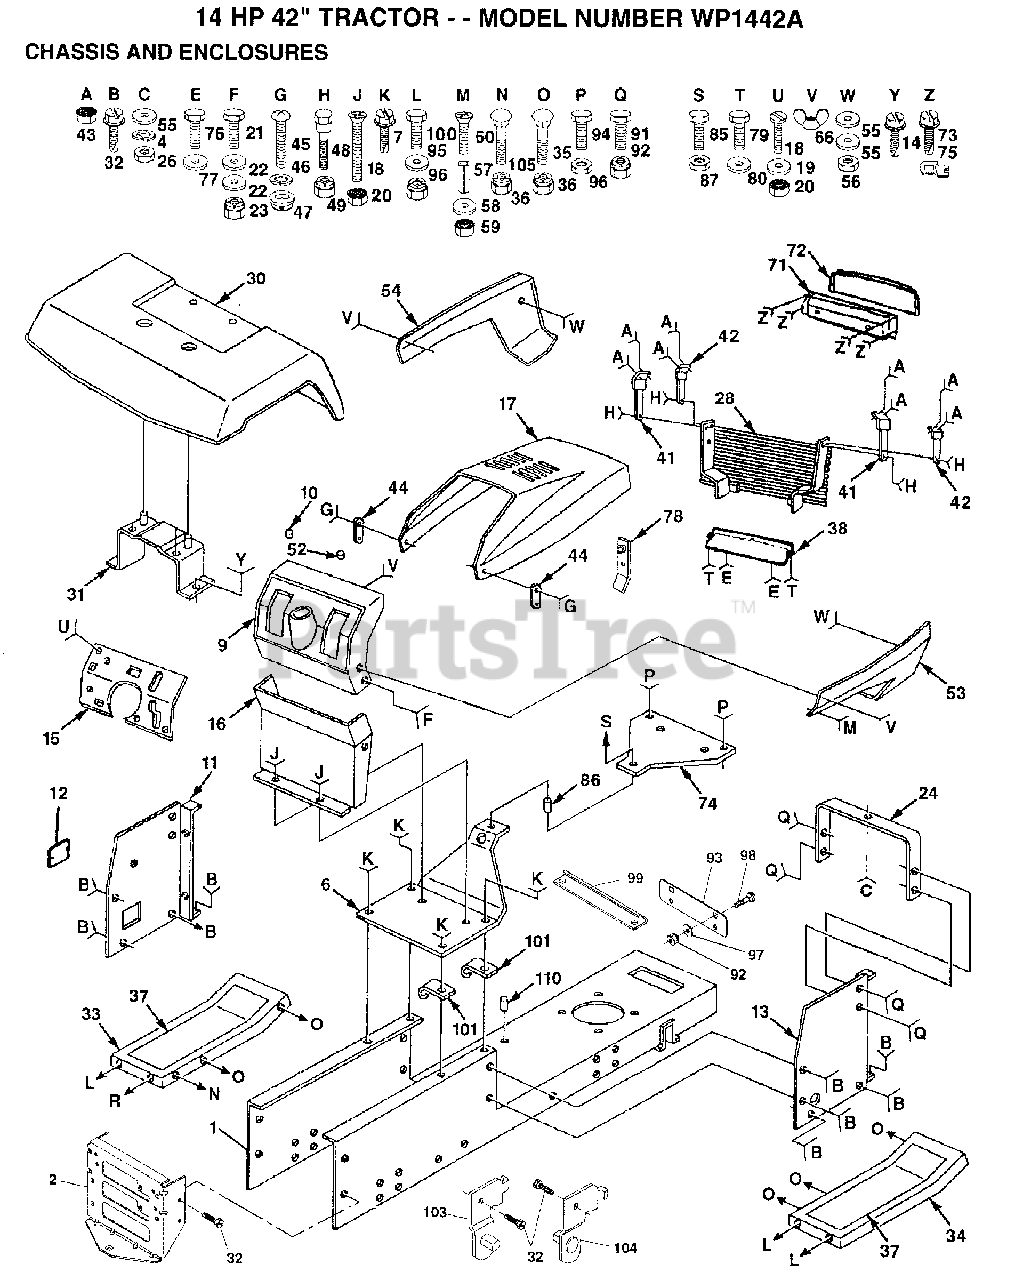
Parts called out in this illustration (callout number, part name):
4	LOCKWASHER
7	SCREW
9	DASHBOARD BLACK
10	PLUG BUTTON T
11	PANEL.DASH.LH
12	COVER ACCESS
13	PANEL.DASH.RH
14	SCREW
15	PLATE.DASH.SILKSC
16	DASH ASSY LT
18	SCREW
19	WASHER
21	BOLT
22	WASHER
23	NUT
24	SUPPORT ASS'Y
30	FENDER
31	BRACKET SUPT FEND
32	SCREW
35	BOLT
36	NUT
37	FOOTREST PAD
43	NUT
44	HOOD LATCH T
45	SCREW
46	LOCKWASHER
47	WELDNUT
52	PLUG-DASH T
54	"PANEL,SIDE LH"
55	WASHER PM
57	SPACER LT
58	WASHER
60	SCREW
72	LENS LT
74	PLATE.SUPT.BATTER
75	"""J"" FASTENER LT"
76	SCREW
77	WASHER
79	SCREW HEX CRT
80	WASHER
85	BOLT
86	SPACER
87	NUT
91	BOLT
92	NUT
93	PLATE EXTEN FEND
94	BOLT
95	WASHER
96	NUT
97	WASHER
99	SPACER FENDER LT
100	BOLT
101	CLIP T
103	BRACKET ASM LH
104	BRACKET ASM RH
